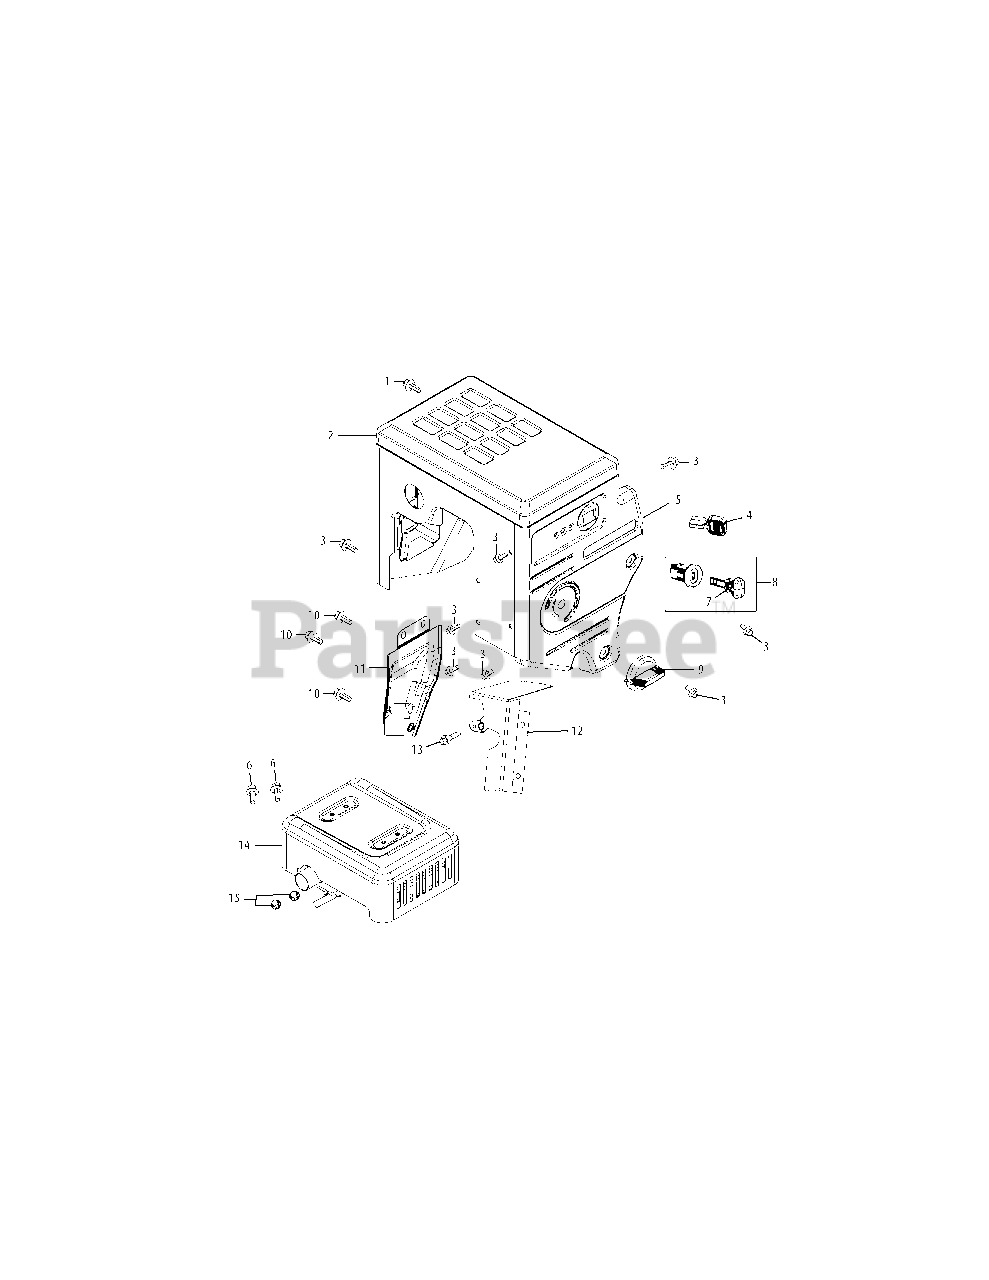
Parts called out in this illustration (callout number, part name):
1	Bolt M 6×16
2	Muffler Shield
3	Bolt M6×12
4	Throttle Control Knob
5	Control Panel
6	Bolt Muffler
7	Key
8	Key Switch Assembly
9	Choke Knob
10	Bolt M6×10
11	Muffler Baffle
12	Carburetor Heat Shield
13	Bolt M6×16
14	Muffler Assembly
15	Nut, M8
